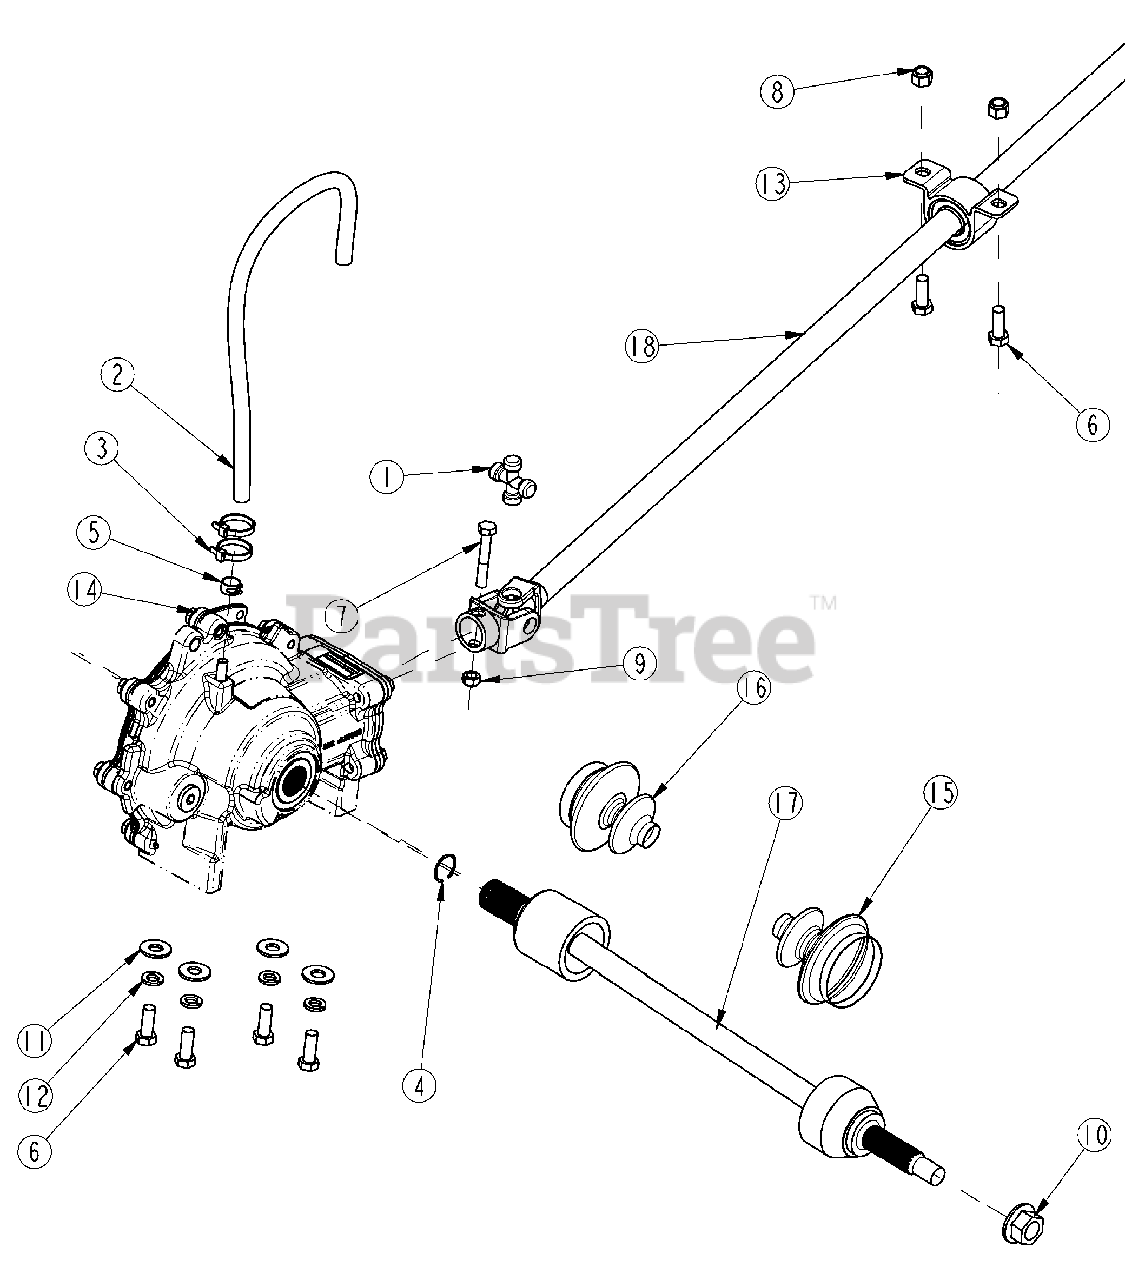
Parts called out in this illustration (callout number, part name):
1	CROSS & BRG KIT
2	VENT HOSE 17.5LG 4X4 GBOX
3	CABLE TIE 2 DIA MIN - BLK
4	SPRING CIR CLIP .95ODX.063WIRE
5	CLAMP PINCH FOR .50 OD HOSE
6	HHCS 3/8-16X1 GR5
7	HHCS 5/16-18X2 GR5
8	NUT LOCK 3/8-16 NYLON INSERT
9	NUT HEX NYLOCK 5/16-18 PLT
10	NUT HEX M16X1.5 TOP LOCK PLT
11	WASHER FLAT 3/8 USS PLT
12	WASHER LOCK SPRING 3/8 PLT
13	PILLOW BLOCK BEARING TRUCK
14	FRONT DIFFERENTIAL W/ELE CLTCH
15	OUTER BOOT KIT W/ 2 CLAMPS
16	INNER BOOT KIT W/2 CLAMPS
17	FRONT AXLE SHAFT STANDARD
18	DRIVELINE 4X4 NT/ST
